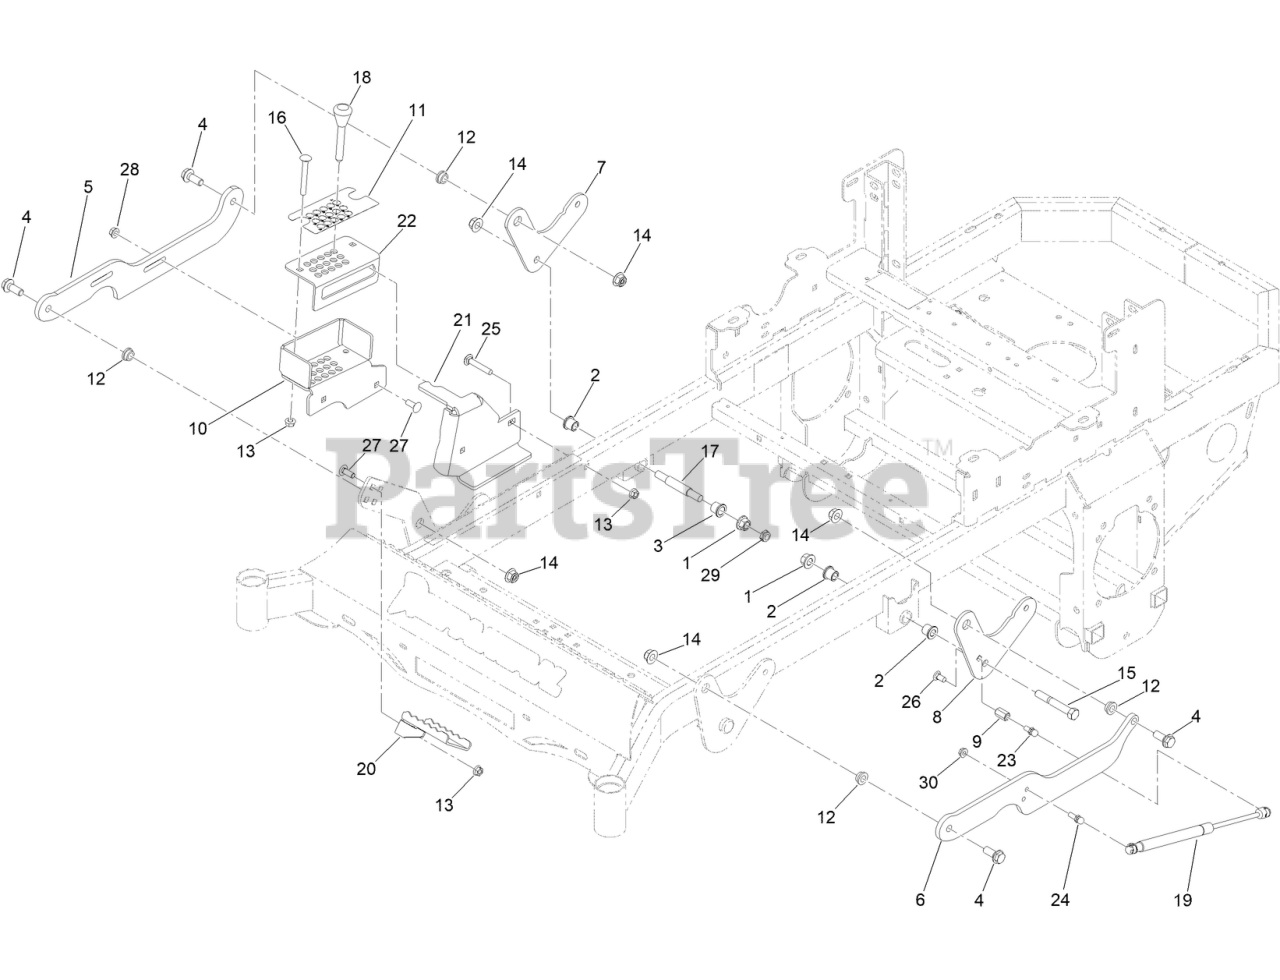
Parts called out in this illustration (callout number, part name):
1	NUT-LOCK
2	BUSHING-FLANGE
3	BUSHING-FLANGE
4	1/2-13X1.25IN HEX FLANGE BOLT (GR.8) YZ
5	2024 DECK HEIGHT ARM RT LINK
6	LINK-DECKLIFT
7	ARM-DECKLIFT REAR (1/4")
8	ARM-DECKLIFT REAR (1/4")
9	HEX COUPLING NUT - REDUCER (3/8" TO 5/16
10	BRACKET PIN SYSTEM (BOTTOM) PAINTED GREY
11	DECAL-HEIGHT OF CUT
12	1/2IN ID X 3/4IN OD X 3/8IN FLANGE BUSH
14	1/2-13 HEX FLANGE 2-WAY REV CNTR L/NYZ
15	1/2-13 X 3-1/2 HEX C/S GR 5 ZINC YELLOW
16	(3/8-16 X 3 CARRIAGE BOLT (GR.5) ZC/YEL)
17	RR DECK HEIGHT BOLT (MACHINED)
18	MAGNETIC PIN FOR STAND ON MWR
19	RZ DECK ASSIST GAS SPRING
20	MWR DECK HEIGHT FOOT PEDAL PAINT
21	2022 DECK LOCK PIN TUBE BRKT
22	2022 DHI PIN ARM LINK TOP BRKT
23	5/16-18X1.286 DAMPER BALL STUD (.562 TL)
24	5/16-18X1.286 DAMPER BALL STUD (.562 TL)
25	SCREW-CARR
26	3/8 X 3/4IN GR 8 CARR BOLT ZINC
27	SCREW-CARR
28	NUT-HHF, WHIZ
29	NUT-HEX
30	NUT-HF
